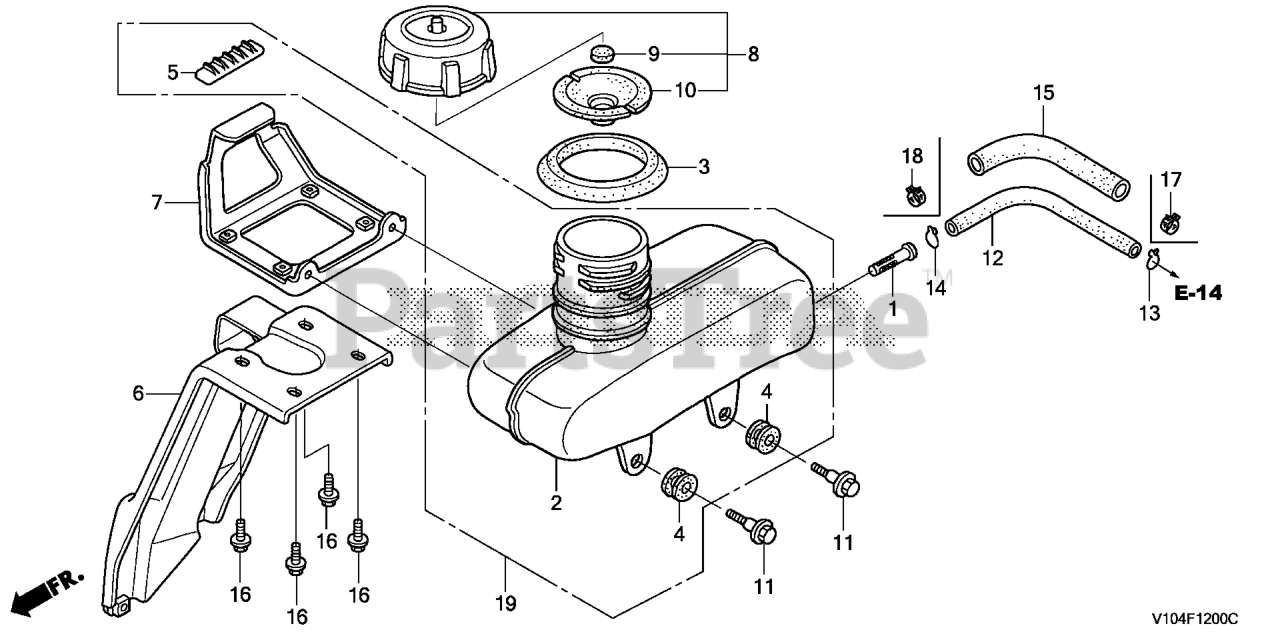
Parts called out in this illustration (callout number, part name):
1	FILTER, FUEL
2	TANK, FUEL
3	SEAL, FUEL FILLER NECK
4	RUBBER A, TANK MOUNTING
5	RUBBER B, TANK MOUNTING
6	BRACKET A, FUEL TANK
7	BRACKET B, FUEL TANK
8	CAP ASSY., FUEL TANK
9	SPONGE, FUEL CAP BREATHER
10	GASKET, FUEL CAP
11	BOLT, SPECIAL (6MM)
12	TUBE, FUEL TANK (FKM)
16	BOLT, FLANGE (6X10)
17	CLAMP, TUBE (D10)
18	CLAMP, TUBE (D12)
